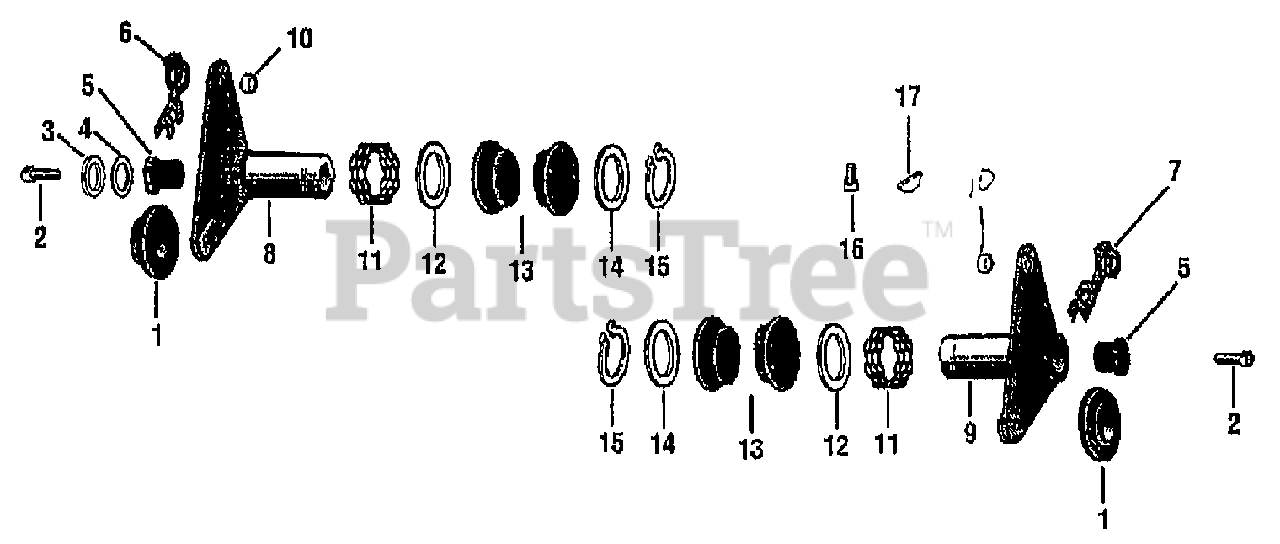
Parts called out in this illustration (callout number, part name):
1	HUB-WHEEL SPACER
2	SCR-HXSKT 1/4-20X.75 NYL
3	WASHER-.92X.5X.03 HT
4	WASHER-.92X.5X.016 HT
5	BEARING-CARRIER (PLASTIC)
6	CLIP-ROD LH
7	CLIP-ROD RH
8	ARM-WHEEL LT
9	ARM-WHEEL RT
10	BUSHING-NYLINER (PLASTIC)
11	SPRING-CREST
12	WASHER-THRUST
13	BEARING-AXLE ARM REAR
14	WASHER-SPEC
15	RING-HEAVY EXT .984 ID
16	SCR-SET SQ 1/4-20 W/NYLOC
17	KEY-WOODRUFF .125X.5
